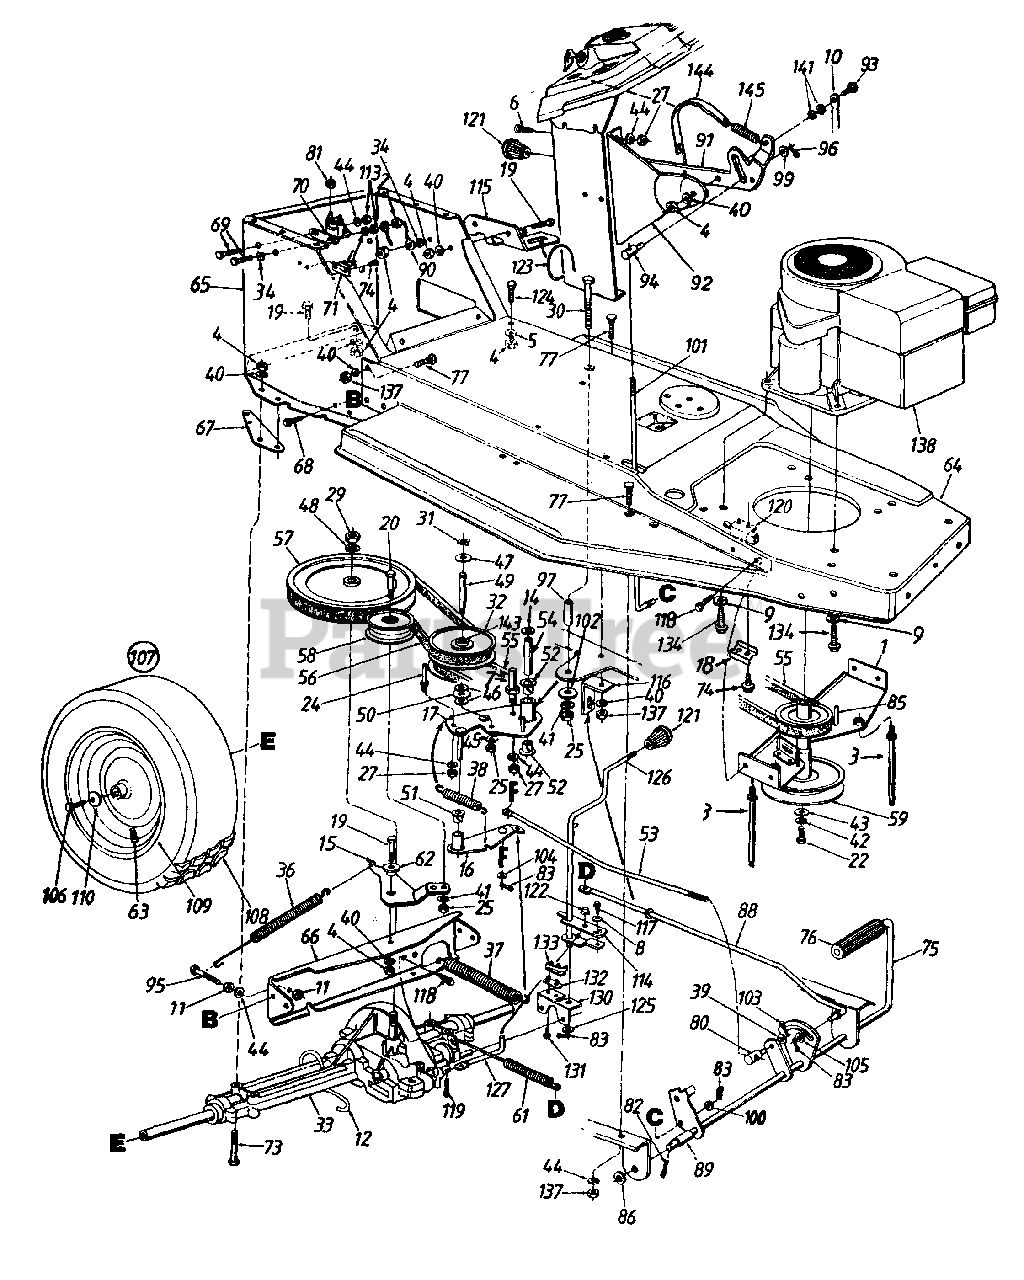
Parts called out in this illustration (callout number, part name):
3	Belt Guard Pin 5/16-18 x 4.75" Lg.
4	Hex Nut 5/16-18 Thd.
5	Bell-Washer .345" I.D. x .88
6	Truss-Mach. Scr. 1/4-20 x .50"
7	Belt Guard Pin 1/4-20 Thd.
8	Bell-Washer .265" I.D. x .75
9	Flat Washer 3/8" I.D. x .97" O.D.
12	Spring Retainer Brkt.
14	Flat Washer 3/8" I.D. x 1.26" O.D.
19	Hex Bolt 5/16-18 x .75" Lg.
20	Hex Bolt 3/8-24 x 2.0" Lg. Gr. 5
22	Hex Bolt 7/16-20 x 1.5" Lg.
24	Belt Guard Pin
25	Hex Nut 3/8-24 Thd.
27	Hex Nut 1/4-20 Thd.
29	Hex Jam Nut 9/16-18 Thd.
30	Hex Bolt 3/8-24 x 3.75" Lg.
31	Snap Ring
32	Variable Speed Pulley Ass'y.
33	Transaxle Ass'y. Comp.
34	Ext. Lock Washer 5/16" I.D.
36	Extension Spring 6.12" Lg.
37	Extension Spring 6.74" Lg.
38	Extension Spring 2.59" Lg.
39	Flat Washer .385" I.D. x.620"
40	Lock Washer 5/16" I.D.
41	Lock Washer 3/8" I.D.
42	Lock Washer 7/16" I.D.
43	Flat Washer .450" I.D. x 1.25"
44	Lock Washer 1/4" I.D.
45	Bell-Washer .39" I.D. x 1.13"
46	Flat Washer .56" I.D. x 1.0" O.D.
47	Washer Teflon .565 I.D.
48	Bell-Washer 9/16" I.D. x 1.125" O.D.
49	Shaft .56" Dia. x 3.875" Lg.
50	Thrust Brg. 1.25 O.D.
51	Flanged Nyliner Brg.
52	Nyliner Flanged Brg.
53	Speed Control Rod
54	Spacer
55	V-Belt
56	V-Belt
57	V-Pulley 8" Dia.
58	Idler Pulley 3-1/8" Dia.
59	Engine Pulley 6.0" Dia. x 3.56"
61	Extension Spring 7.08" Lg.
62	Shld. Spacer .500" Dia.
63	Air Valve
69	Hex Bolt 1/4-20 x .62" Lg.
70	Solenoid
71	Circuit Breaker
73	Hex Bolt 5/16-18 x 2.75" Lg.
74	Truss Mach. B-Tap Scr. #10 x .50" Lg.
77	Ribbed Neck Bolt 5/16-24 x .84"
80	Ferrule
81	Hex Sems Nut 1/4-20 Thd.
82	Cotter Pin 1/8" Dia. x 1.25" Lg.
83	Cotter Pin 3/32" Dia. x .75" Lg.
85	Sq. Key 1/4 x 2.0" Lg.
86	Flat Washer .635" I.D. x 1.0"
88	Brake Rod
89	Spacer 5/8" I.D. x 1.2" Lg.
90	Ground Wire 7.25" Lg.
91	Speed Selector Lever
92	5 Spd. Selector Brkt. (450 Series)
93	Shld. Bolt .437" Dia. x .47" Lg.
94	Ferrule
95	Hex Bolt 1/4-28 x 1.25" Lg.
96	Internal Cotter Pin 5/16" Dia.
97	Spacer .375" I.D. x .625"
99	Flat Washer .344" I.D. x .62"
100	Flat Washer .25" I.D. x .62" O.D.
101	Speed Control Rod
102	Flat Washer 3/8" I.D. x 1.25" O.D.
103	Cotter Pin 1/8" Dia. x 1.0" Lg.
104	Flat Washer .34" I.D. x .68"
105	Flat Washer .34" I.D.
106	Hex Lock Bolt 5/16-24 x .75" Lg.
110	Bell-Washer .345" I.D. x .88"
113	Hex Jam Nut 1/4-20 Thd.
114	Shift Lever Adjusting Link
115	Shift Lever Spring Brkt.
118	Hex Washer Hd. Tap Scr. 1/4-20 x .5" Lg.
119	Internal Cotter Pin
120	Safety Switch (Clutch)
121	Knob
122	Retaining Ring
123	Compression Spring 1.5" Lg.
124	Hex Washer Hd. Scr. 5/16-18 x 7/8" Lg.
125	Flat Washer .469" I.D. x .88"
130	Shift Lever Support
131	Hex Washer Hd. #8 x .50" Lg.
132	Insulator Nut Plate
133	Spring Switch
134	Hex Tap Scr. 3/8-16 x 1.25"
137	Hex Nut 5/16-24 Thd.
138	Engine
141	Wave Washer .445" I.D.
143	Needle Brg.
144	7 Spd Indicator Strip (470 Series)
145	Ext. Spring 2.04" Lg. (Style 0, 1)
